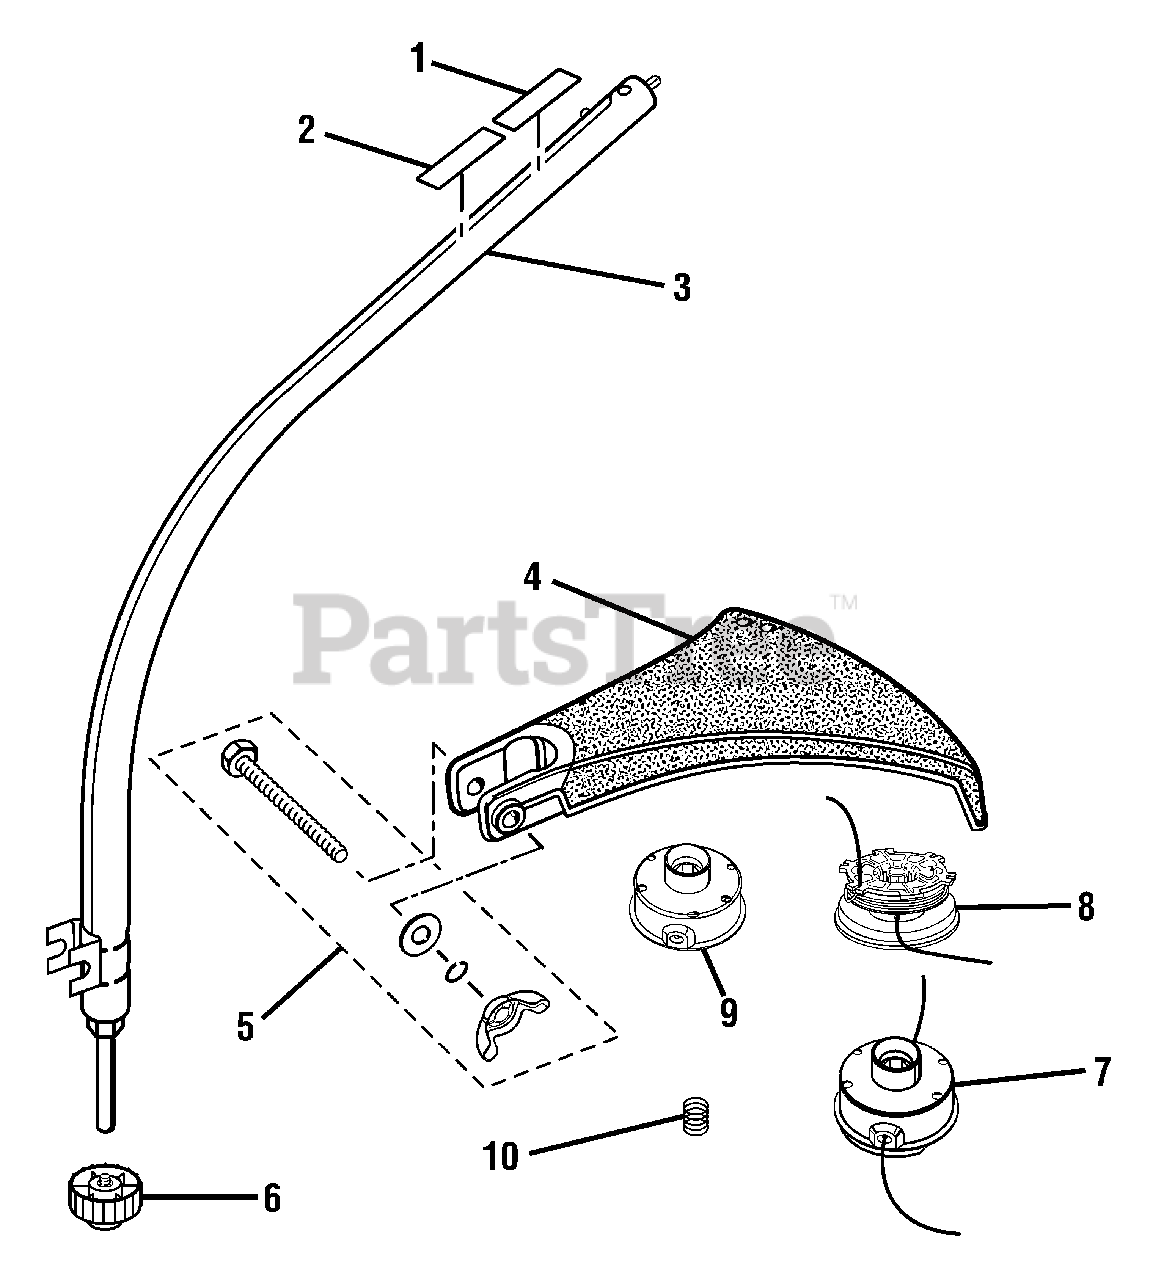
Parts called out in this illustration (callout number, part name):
1	EXPAND-IT LABEL
2	WARNING LABEL
3	CURVED SHAFT ASSEMBLY
4	GRASS DEFLECTOR
5	FASTENER PARTS KIT
6	SPOOL RETAINER (RHT) (ITEM NO. AP04106)
7	COMPLETE STRING HEAD (.080 in.) (ITEM NO. AP04114)
8	SPOOL AND STRING (.080 in.) (ITEM NO. AH04112)
9	HOUSING AND EYELET
